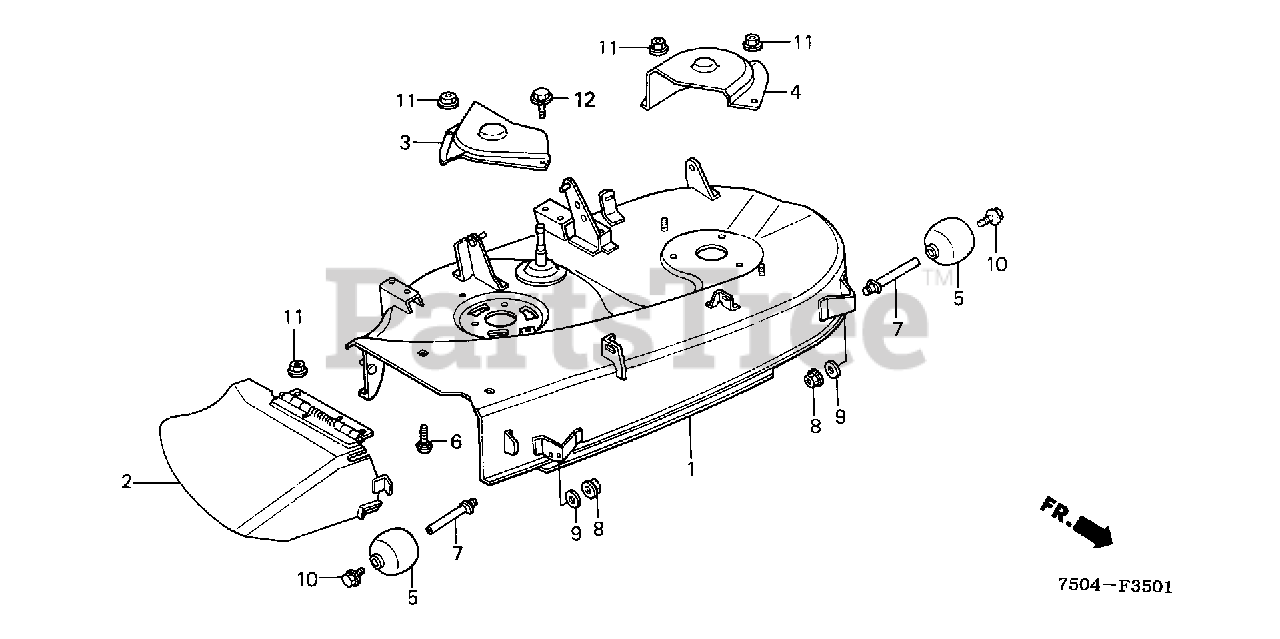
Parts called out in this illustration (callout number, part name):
1	HOUSING, CUTTER
1	HOUSING, CUTTER (NOT AVAILABLE)
2	ADAPTER, DISCHARGE *NH190M* (VINTAGE GRAY METALLIC) (NOT AVAILABLE)
3	COVER, R. BELT *NH190M* (VINTAGE GRAY METALLIC)
4	COVER, L. BELT *NH190M* (VINTAGE GRAY METALLIC) (NOT AVAILABLE)
5	ROLLER, ANTI-SCALP
6	BOLT, SPECIAL (9X15)
7	SHAFT, ANTI-SCALP ROLLER
8	NUT, SELF-LOCK (12MM)
9	WASHER, THRUST (12MM)
10	BOLT-WASHER (8X12)
10	BOLT-WASHER (8X16)
11	NUT, FLANGE (8MM)
12	BOLT, FLANGE (8X14)
